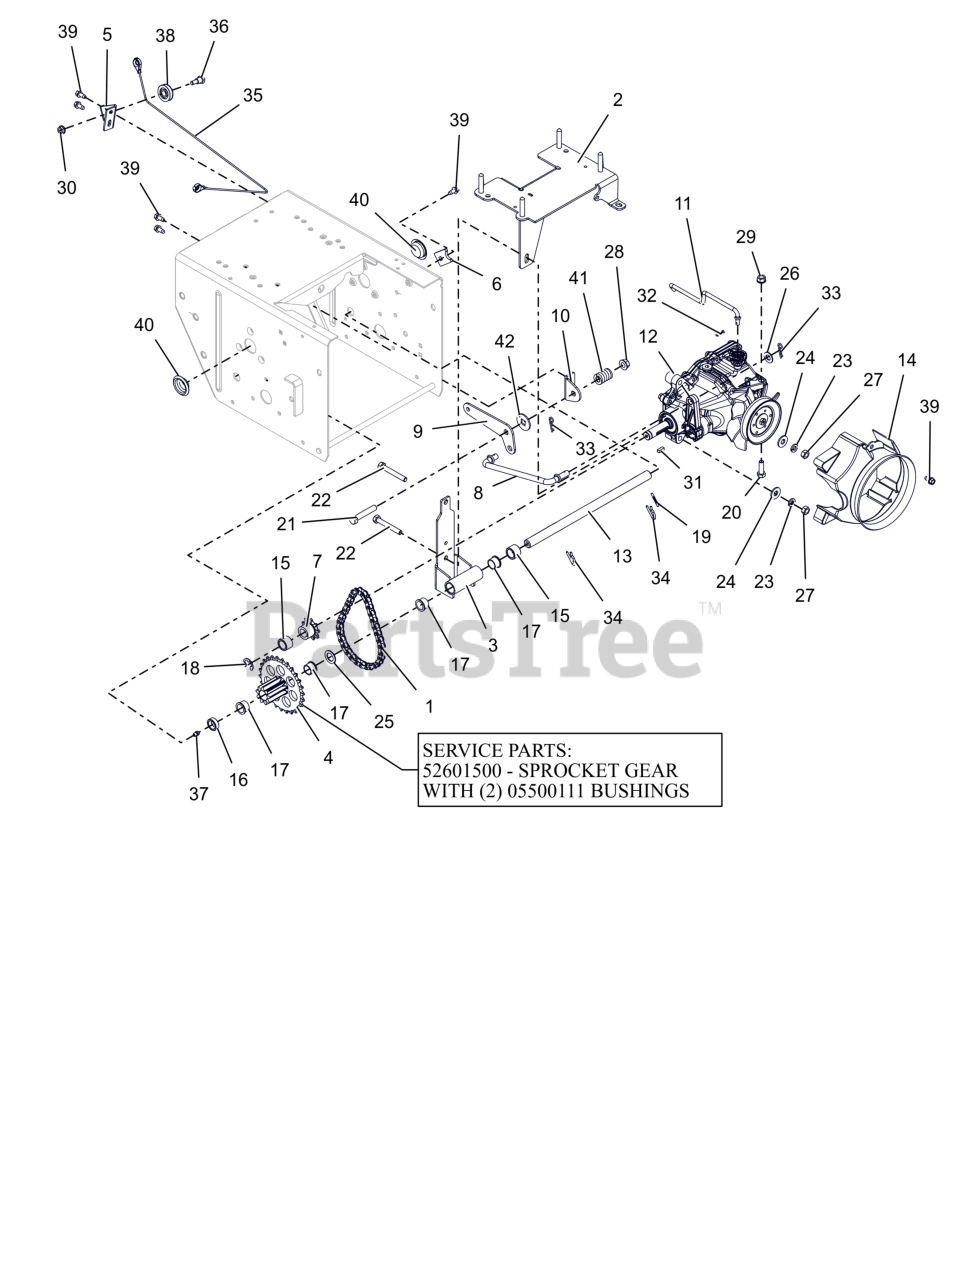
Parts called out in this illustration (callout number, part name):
1	CHAIN - #41, 32 PITCHES
2	BRACKET, HYDROSTATIC TRANS XLG
3	TRANS MOUNT, TENSIONING, WHEEL
4	PINION & SPROCKET
4	PINION & SPROCKET W/BUSHINGS
5	BRACKET, CABLE PULLEY
6	TAB, ANTI ROTATION
7	SPROCKET, PINION 9T W/KEY
8	ROD, HYDRO TRANS SHIFT
9	PIVOT, HYDRO TRANS SHIFT
10	BRACKET, HYDRO SHIFT PIVOT
11	ROD, HYDRO BYPASS
12	TRANSMISSION, HYDROSTATIC
13	SHAFT, PINION - HARDENED
14	SHROUD, HYDROGEAR RT-310
15	SPACER, .635X.880X.611
16	BSHG-SLV, .635X.880X.305
17	BSHG-FLG .625X.750X.500X.875
18	RG-RTNG-EXT .625X.042
19	@PIN-GRV .125X1.00 TP E ALLOY
20	BLT,HEX .31-18X1.00 G5 ZCC
21	BLT,HEX .38-16X2.00 G5 ZCC
22	BLT, HEX .31-18X2.25 G5 ZCC
23	WSHR, LK-HVY .312X.097 ZCC
24	WSHR,FLT .375X.875X.083 ZCC
25	WSHR, FLT .630X1.005X.062 ZCC
26	WSHR,FLT .406X.812X.065 ZCC
27	NUT, HEX .312-18 ZCC
28	NUT-LK-TOP-FLG .38-16 ZC120
29	NUT-LK-TOP-FLG .312-18 GF ZCC
30	NUT-LK-TOP-FLG .250-20 GF ZCC
31	KEY-SQ .187 X .50 X .187
32	PIN, HAIR #178 .06X.77 ZCC
33	PIN, HAIR #213 .08X1.19 ZCC
34	PIN, SPRING CLIP
35	CABLE, TRACTION, HYDRO PRO
36	BOLT, SHLDR -.375 X .375 X .25-20
37	ZERK,FITTING .25X.125 DRIVE IN
38	PULLEY, CABLE
39	SCR-TAP .25-20X.50 HWH ZCC
40	PLUG, HOLE - 1.125"
41	SG-COMP .187X.56X1.62
42	FRICTION WASHER
